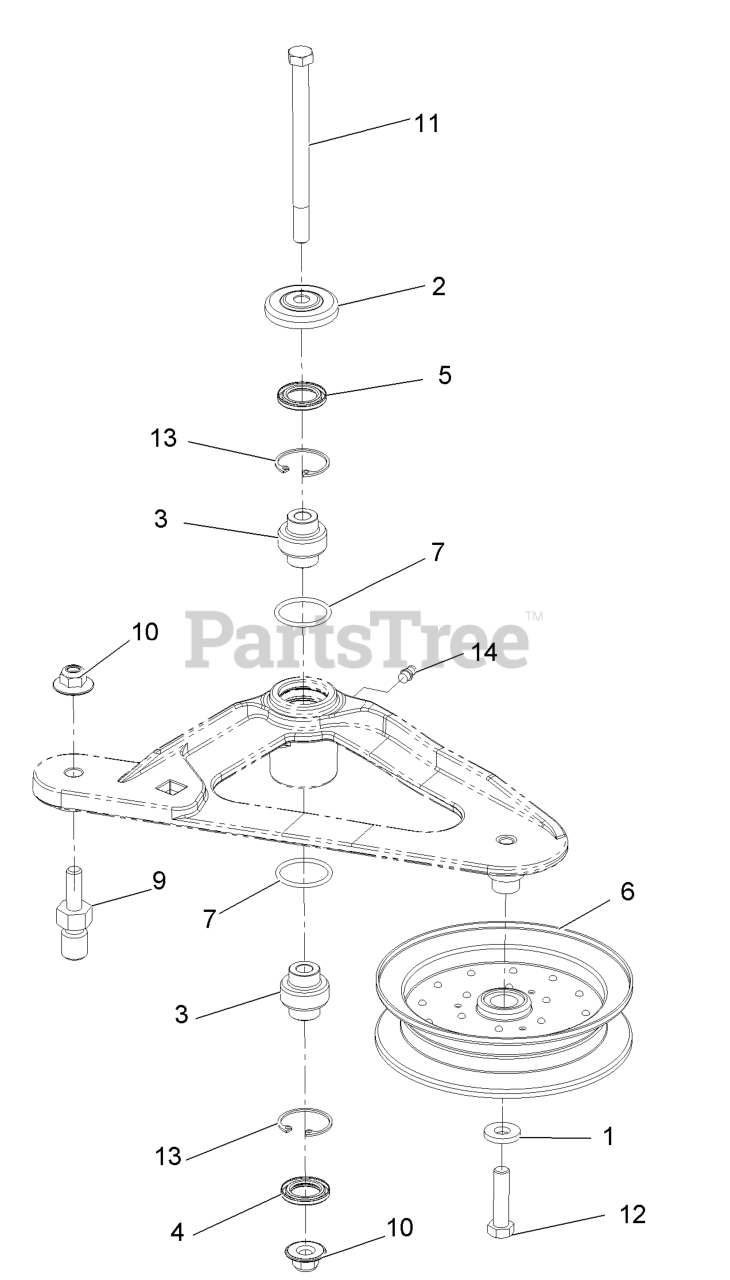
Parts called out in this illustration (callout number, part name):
2	GUARD-TOP
3	BEARING-SPHERICAL
4	SEAL-LIP, DOUBLE
5	SEAL-LIP, SINGLE
10	Nut-Nyloc 3/8-16 Flg
11	SCREW-SHOULDER, HH
12	SCREW-HH
13	RING-SNAP
14	FITTING-GREASE
